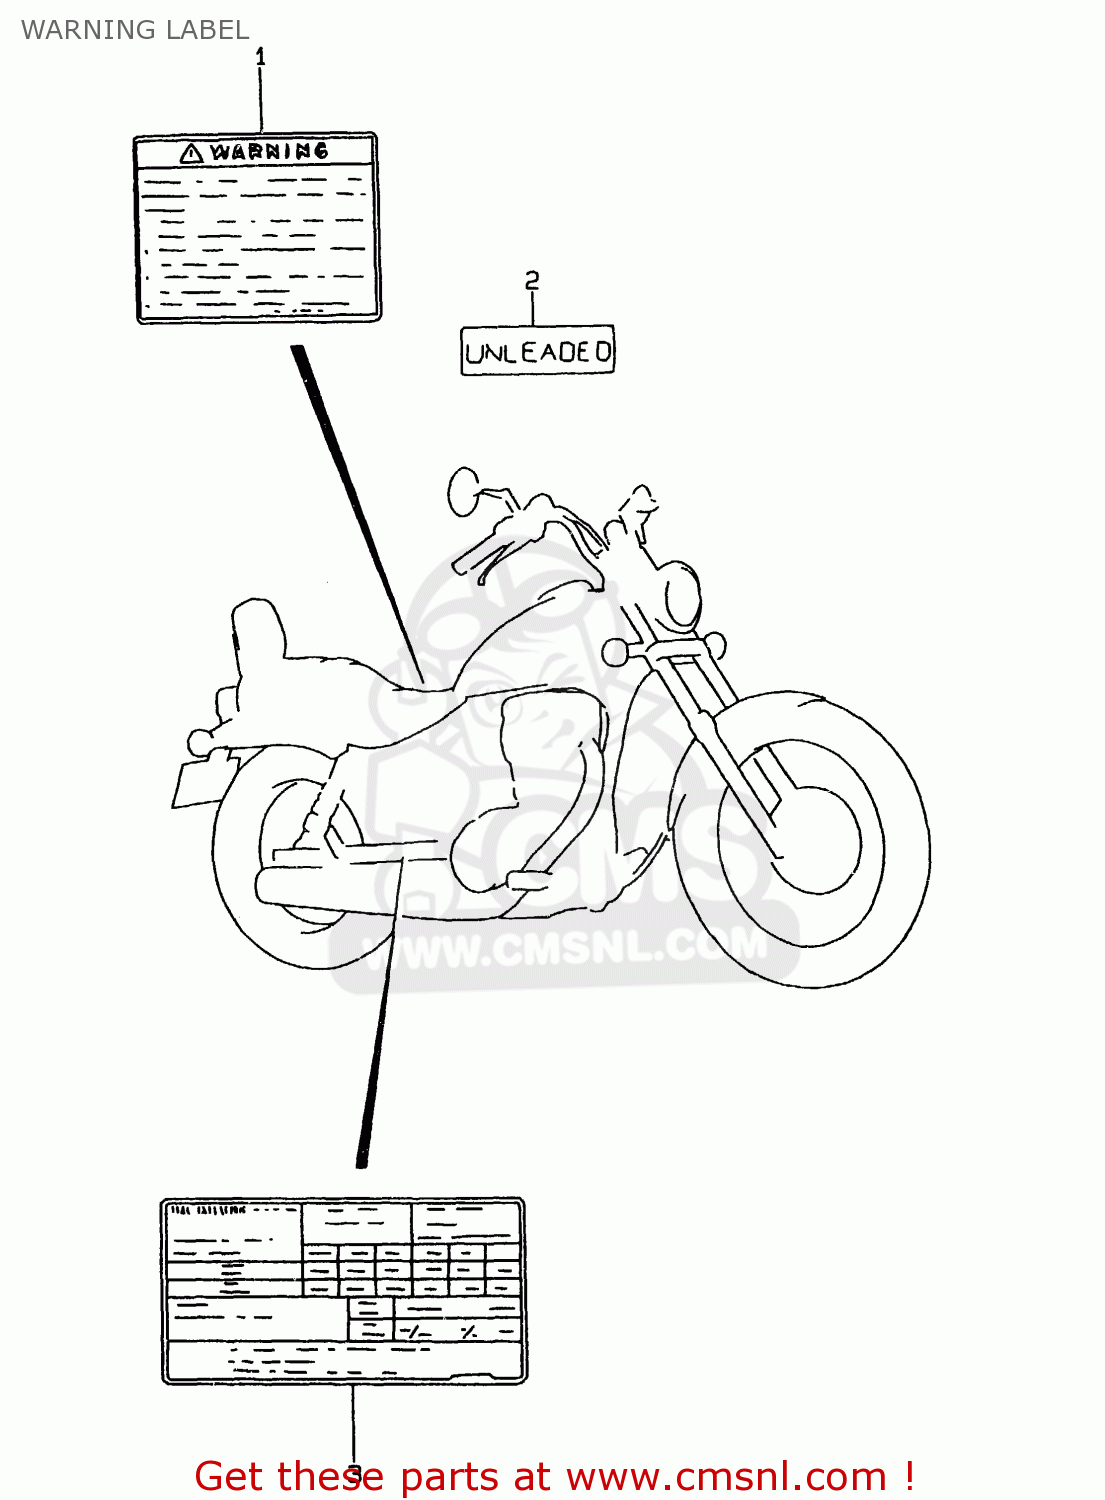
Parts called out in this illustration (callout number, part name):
1	LABEL,WARNING
2	LABEL,CAUTION
3	LABEL,TIRE AIR PRESSURE
4	MANUAL, OWNER'S
